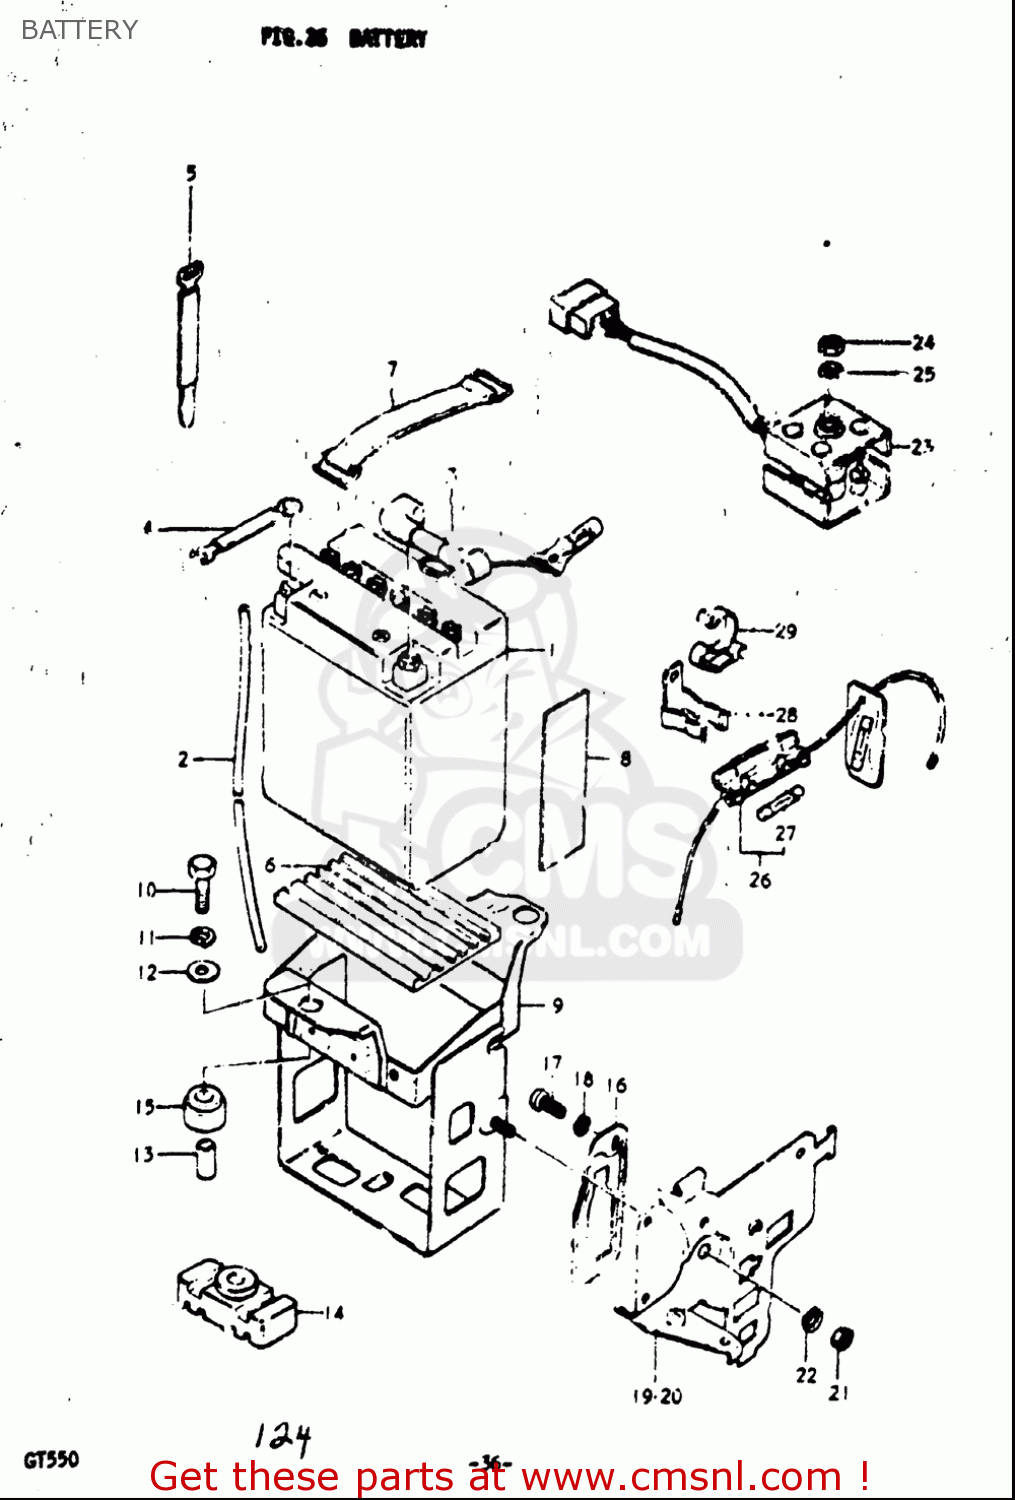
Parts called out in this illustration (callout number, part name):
1	BATTERY ASSEMBLY (12V)
2	HOSE,BATTERY EXHAUST(L:780)
3	LEAD WIRE,BATTERY PLUS
5	CLAMP
6	PROTECTOR,BATTERY
7	BAND
8	PROTECTOR(170X95X3.0)
10	BOLT
11	WASHER,LOCK
12	WASHER(6.5X18X1.6)
13	SPACER(6.1X8X15.5)
17	SCREW
18	WASHER,LOCK
22	WASHER,LOCK
23	RECTIFIER ASSY
24	NUT
25	WASHER,LOCK
26	CASE ASSY,FUSE
27	FUSE(20A)
